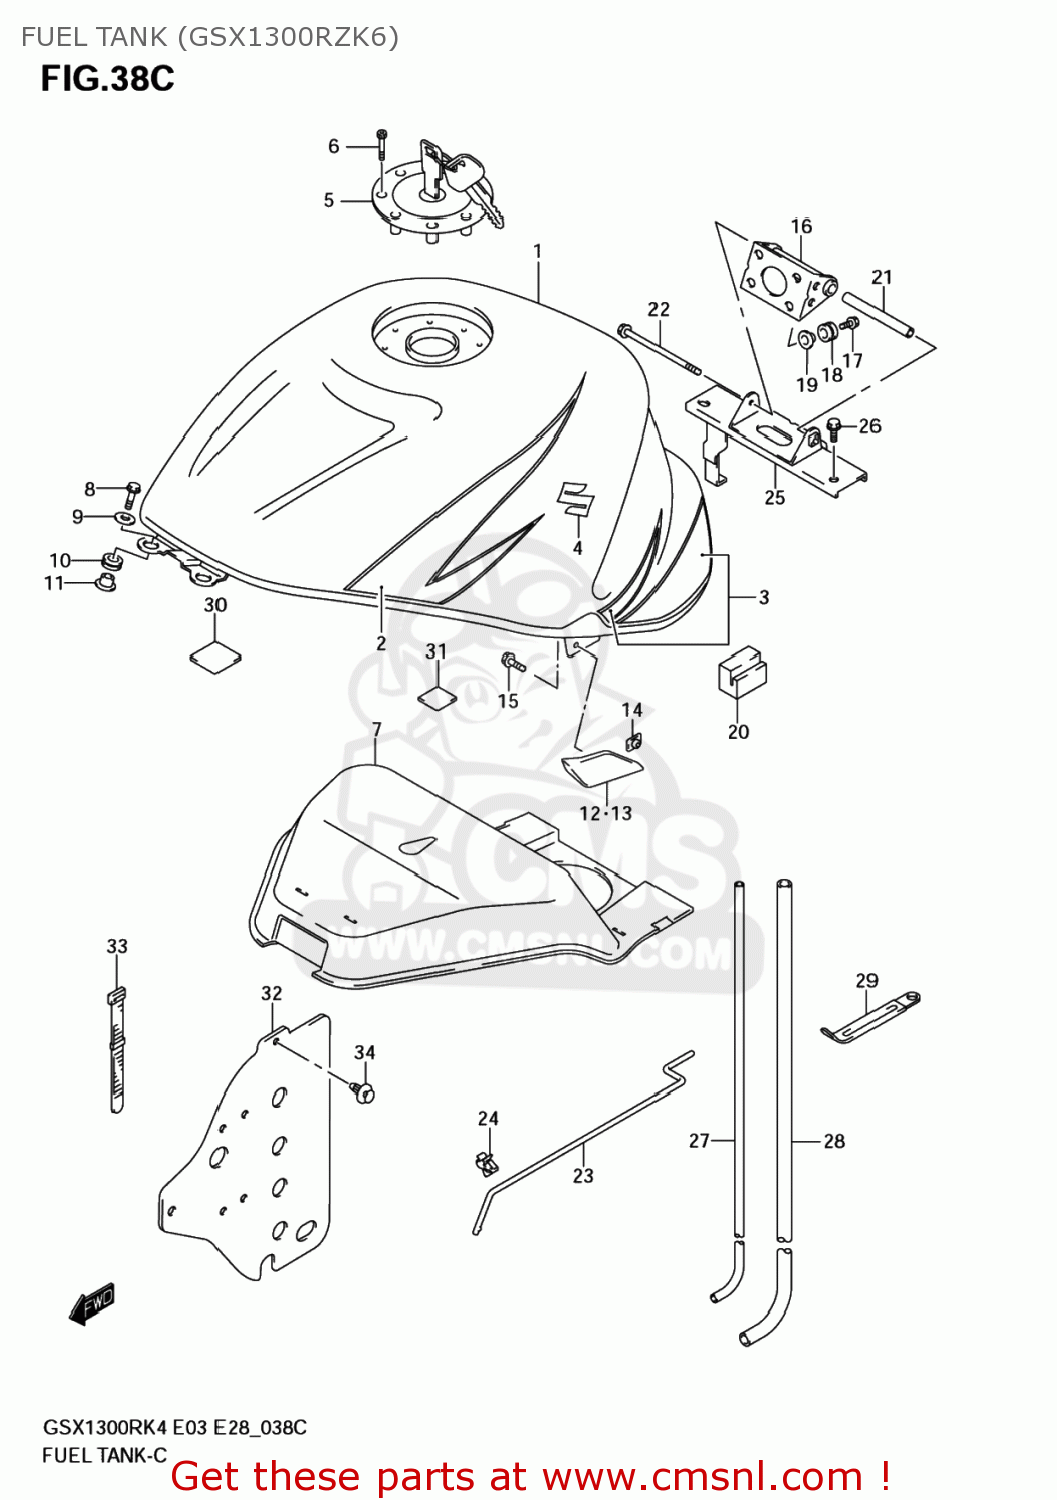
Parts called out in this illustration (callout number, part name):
1	TANK ASSY,FUEL(WHITE)
2	TAPE SET,FUEL TANK
3	TAPE SET,FUEL TANK
4	EMBLEM,S
5	CAP SET,FUEL TANK
6	BOLT(5X20)
7	SHIELD,FUEL TANK HEAT
8	SCREW(6X25)
9	WASHER(6.5X18X1.5)
10	CUSHION
11	WASHER
12	COVER,FUEL TANK SIDE,R
13	COVER,FUEL TANK SIDE,L
14	PLATE,FUEL TANK SIDE
15	SCREW 6X10
16	BRACKET,FUEL TANK RR NO.1
17	BOLT(6X20)
18	CUSHION
19	WASHER
20	CUSHION,FUEL TANK SIDE
21	SPACER,FUEL TANK RR
22	BOLT
23	STAY,FUEL TANK
24	CLAMP
25	BRACKET,FUEL TANK RR NO.2
26	BOLT
27	HOSE,FUELTANK BREATHER
28	HOSE(7X11X600)
29	CLAMP(L:80)
30	CUSHION
31	CUSHION,FUEL TANK COVER
32	SHEET,HEAT SHIELD RUBBER
33	CLAMP(L:165)
34	CLIP(BLACK)
